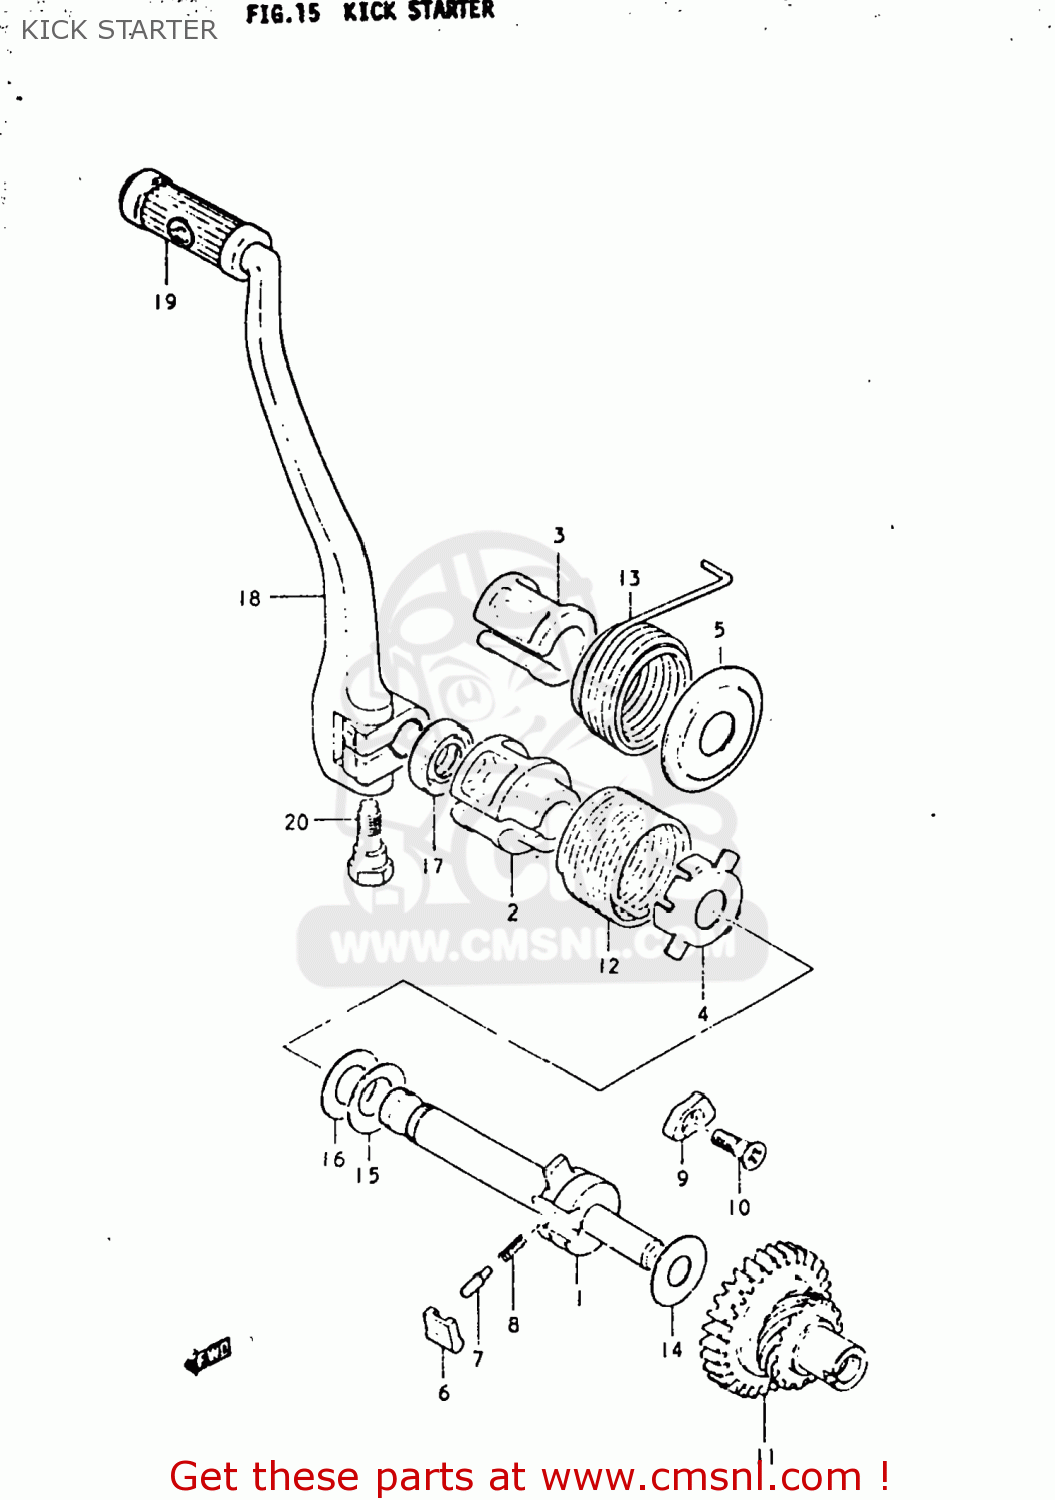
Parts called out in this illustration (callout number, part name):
1	SHAFT,KICK STARTER
2	GUIDE,KICK SHAFT SPRING
3	GUIDE,KICK STARTER SFT SPRING
4	HOLDER,KICK SHAFT SPRING
5	HOLDER,KICK STARTER SHAFT SPR
6	PAWL,KICK STARTER
7	PIN(5X15.5)
8	SPRING
9	LIFTER,KICK STARTER PAWL
10	SCREW(6X19)
11	GEAR,KICK STARTER DRIVE
12	SPRING
13	SPRING
14	WASHER
15	WASHER(16X30X0.5)
16	WASHER
17	SEAL,OIL(16X30X8)
18	LEVER ASSEMBLY,KICK STARTER
19	RUBBER,KICK STARTER PEDAL
20	BOLT
